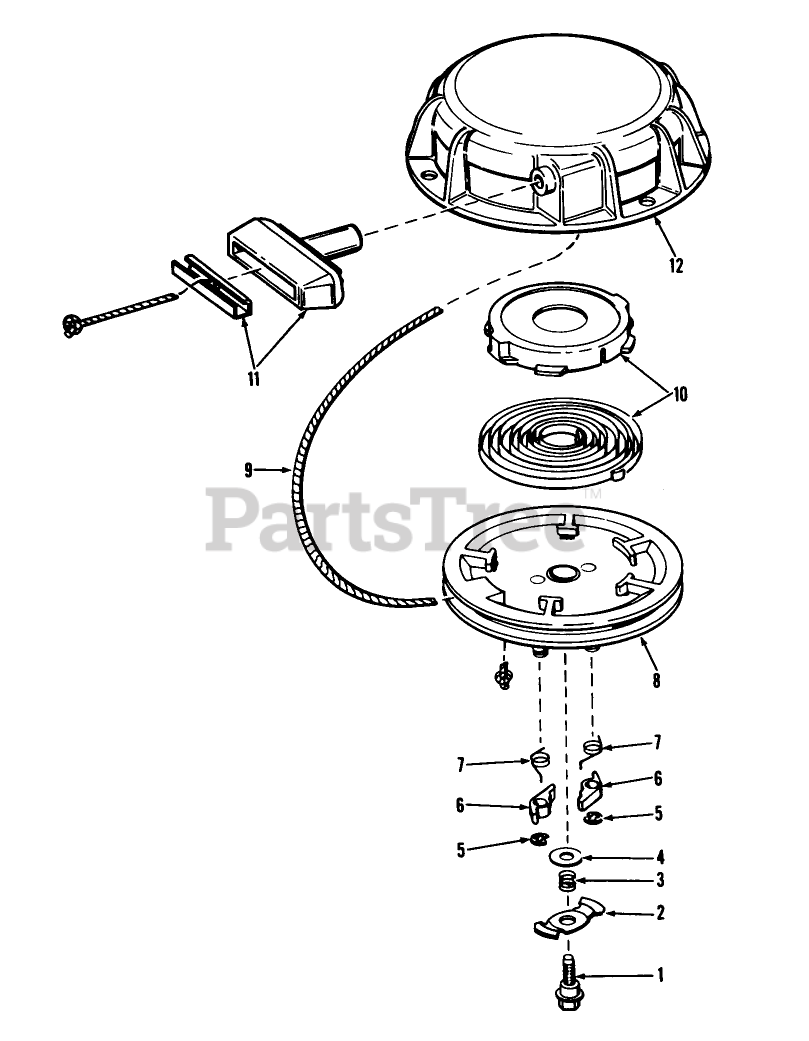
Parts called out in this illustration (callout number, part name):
1	Screw, Center
2	Cam, Dog
3	Spring, Brake
4	Washer, Brake
5	Ring, Retainer
7	Spring, Dog
8	Pulley
9	Rope-Starter
10	Spring & Keeper Assy.
11	Assy., Starter
12	Housing Assy., Starter
